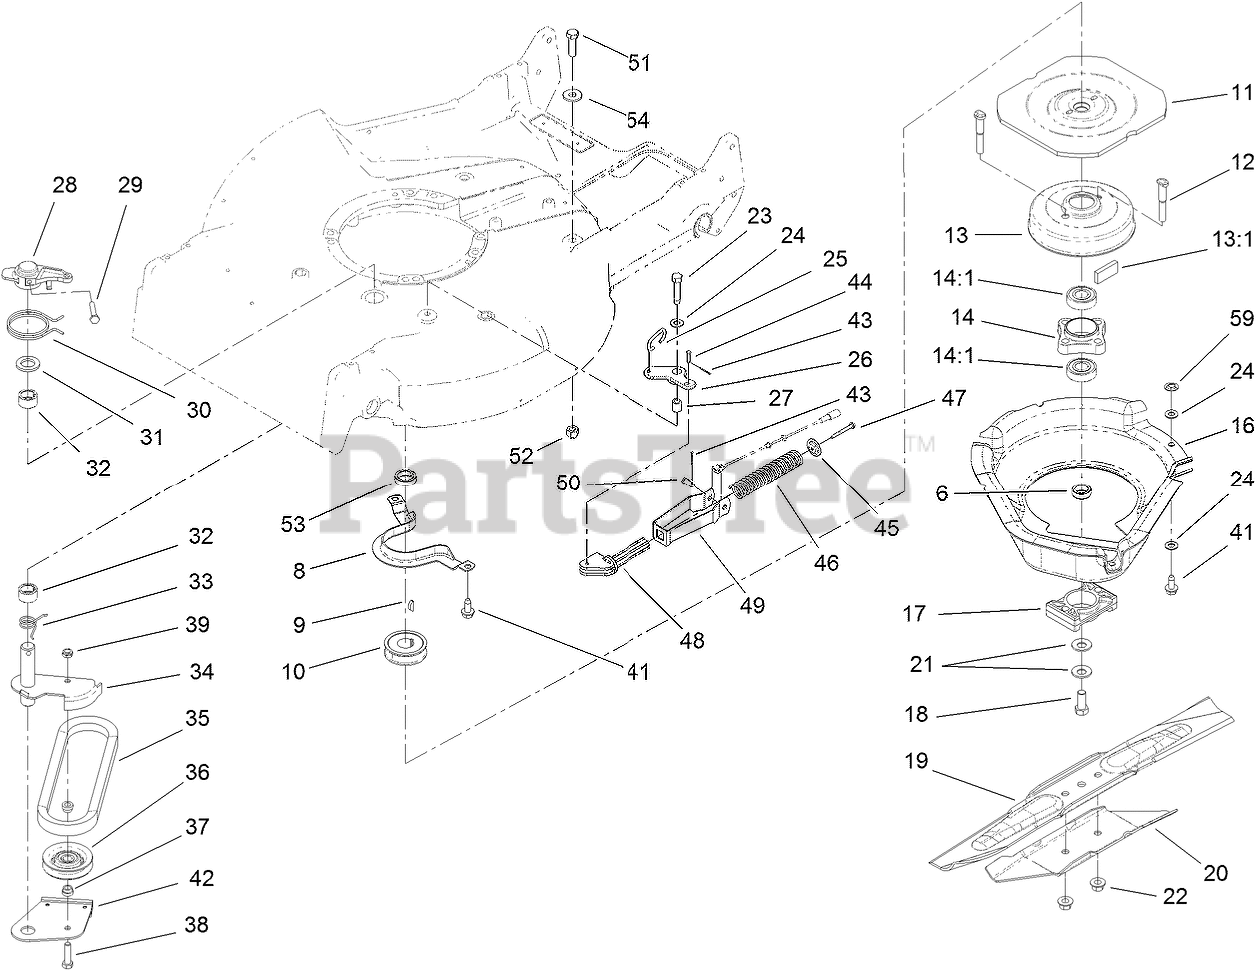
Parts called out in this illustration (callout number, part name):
6	SPACER-SHAFT, OUTPUT
8	BRACKET-GUIDE, BELT
9	KEY-WOODRUFF
10	PULLEY-DRIVER
11	FLYWHEEL-BBC
12	BOLT-BLADE
13	BRAKE DRUM ASM
13:1	DAMPENER-VIBRATION
14	HUB ASM
14:1	BEARING-BALL
16	SHIELD
17	SPACER-BLADE
18	SCREW-HH
19	BLADE-21 INCH
20	STIFFENER-BLADE
21	WASHER-SPRING
22	NUT-LOCK
23	SCREW-HH
24	WASHER-PLAIN
25	LINK-CONTROL
26	BELLCRANK
27	SLEEVE-BELLCRANK
28	LEVER
29	SCREW-HH
30	SPRING-TORSION
31	WASHER
32	BEARING
33	SPRING-TORSION
34	ARM-IDLER
35	V-BELT
36	PULLEY-IDLER
37	SPACER-PULLEY, IDLER
38	SCREW-HH
39	NUT-LOCK, NI
41	SCREW-HWHTF
42	BRAKE PLATE ASM
43	PIN-COTTER
44	PIN-SPRING
45	RETAINER-SPRING
46	SPRING
47	SCREW-HWHTF
48	GUIDE-SPRING
49	BRACKET-SPRING
50	PIN-CABLE
51	SCREW-HH
52	NUT-LOCK, NI
53	SPACER-PULLEY
54	WASHER-HARDENED
59	NUT-PUSH
